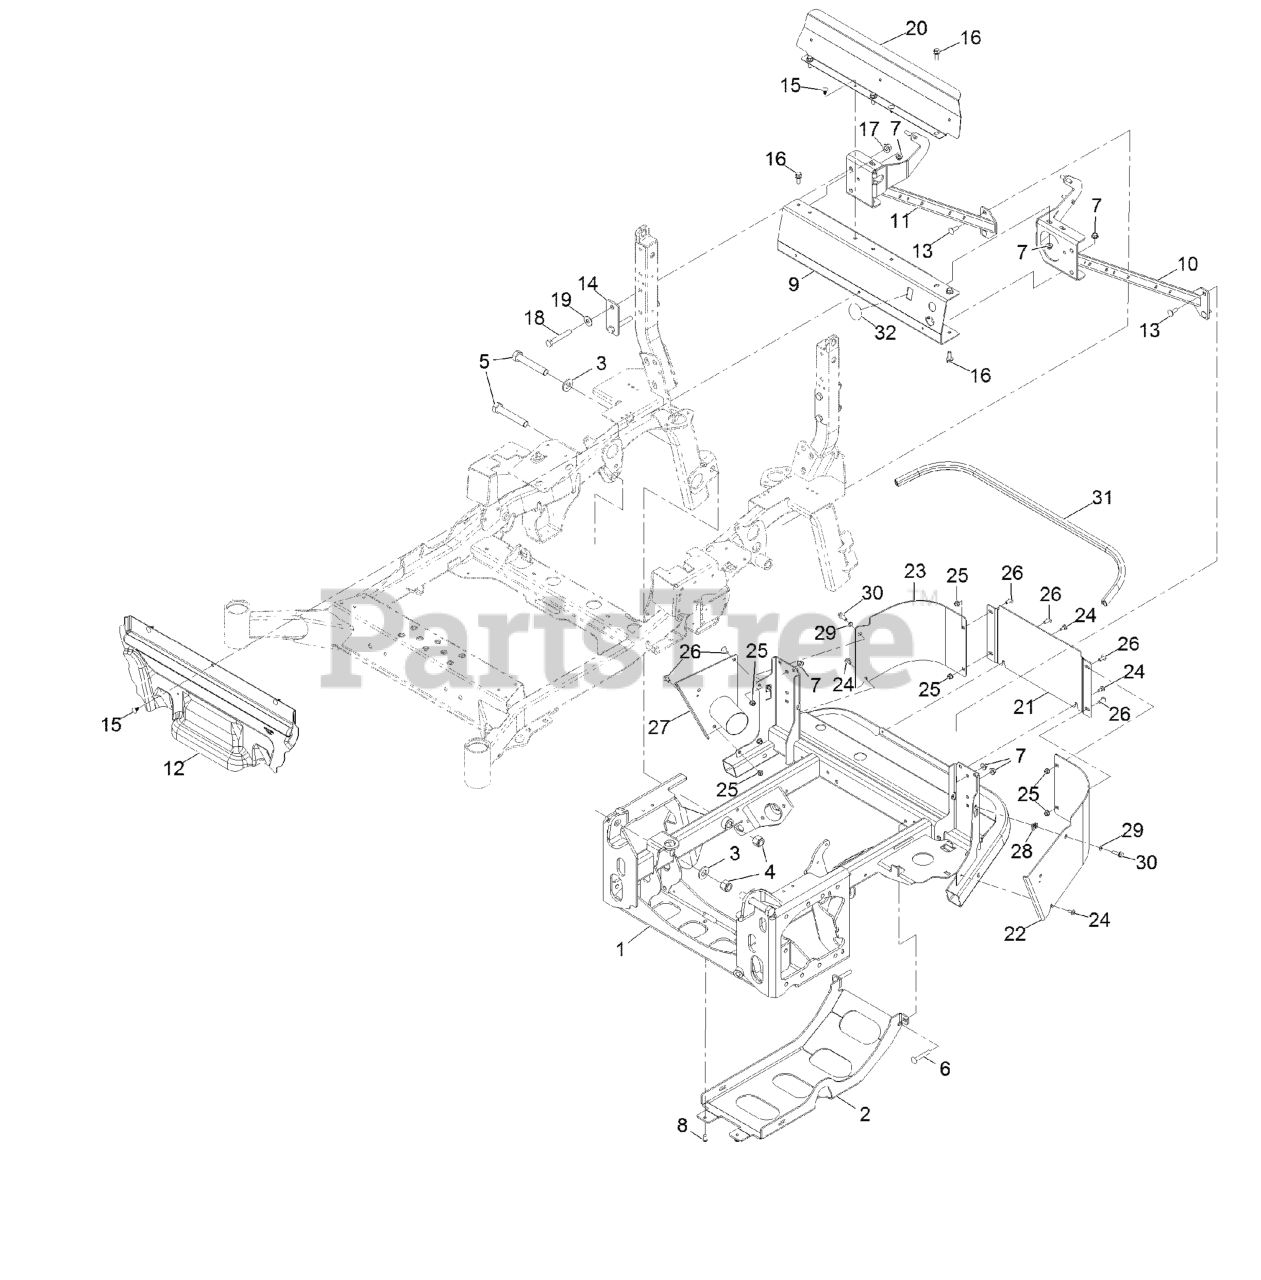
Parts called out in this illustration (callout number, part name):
1	FRAME-POWER
2	PLATE-SKID
4	NUT-LOCK, NI
5	SCREW-HH
6	SCREW-CARR
7	NUT-HF, NI
8	SCREW-BHTF
9	CHANNEL-CROSS
10	BRACE-ROPS, LH
11	BRACE-ROPS, RH
12	PANEL-DEFLECTOR, HEAT
13	SCREW-CARR
14	PLATE-SPACER
15	PLUG-PLASTIC
16	SCREW-HHF
17	Nut-Lock 1/2-13
18	SCREW-HH
19	WASHER-SPRING
20	SHIELD-AIR
21	PLATE-BUMPER, CENTER
22	PLATE-BUMPER, LH
23	PLATE-BUMPER, RH
24	SCREW-SHOULDER
25	NUT-HF, NI
26	SCREW-TORX
27	PLATE-EXHAUST
29	WASHER-BELLEVILLE
30	SCREW-HHF
31	SEAL-BULB
32	DECAL-COVER
